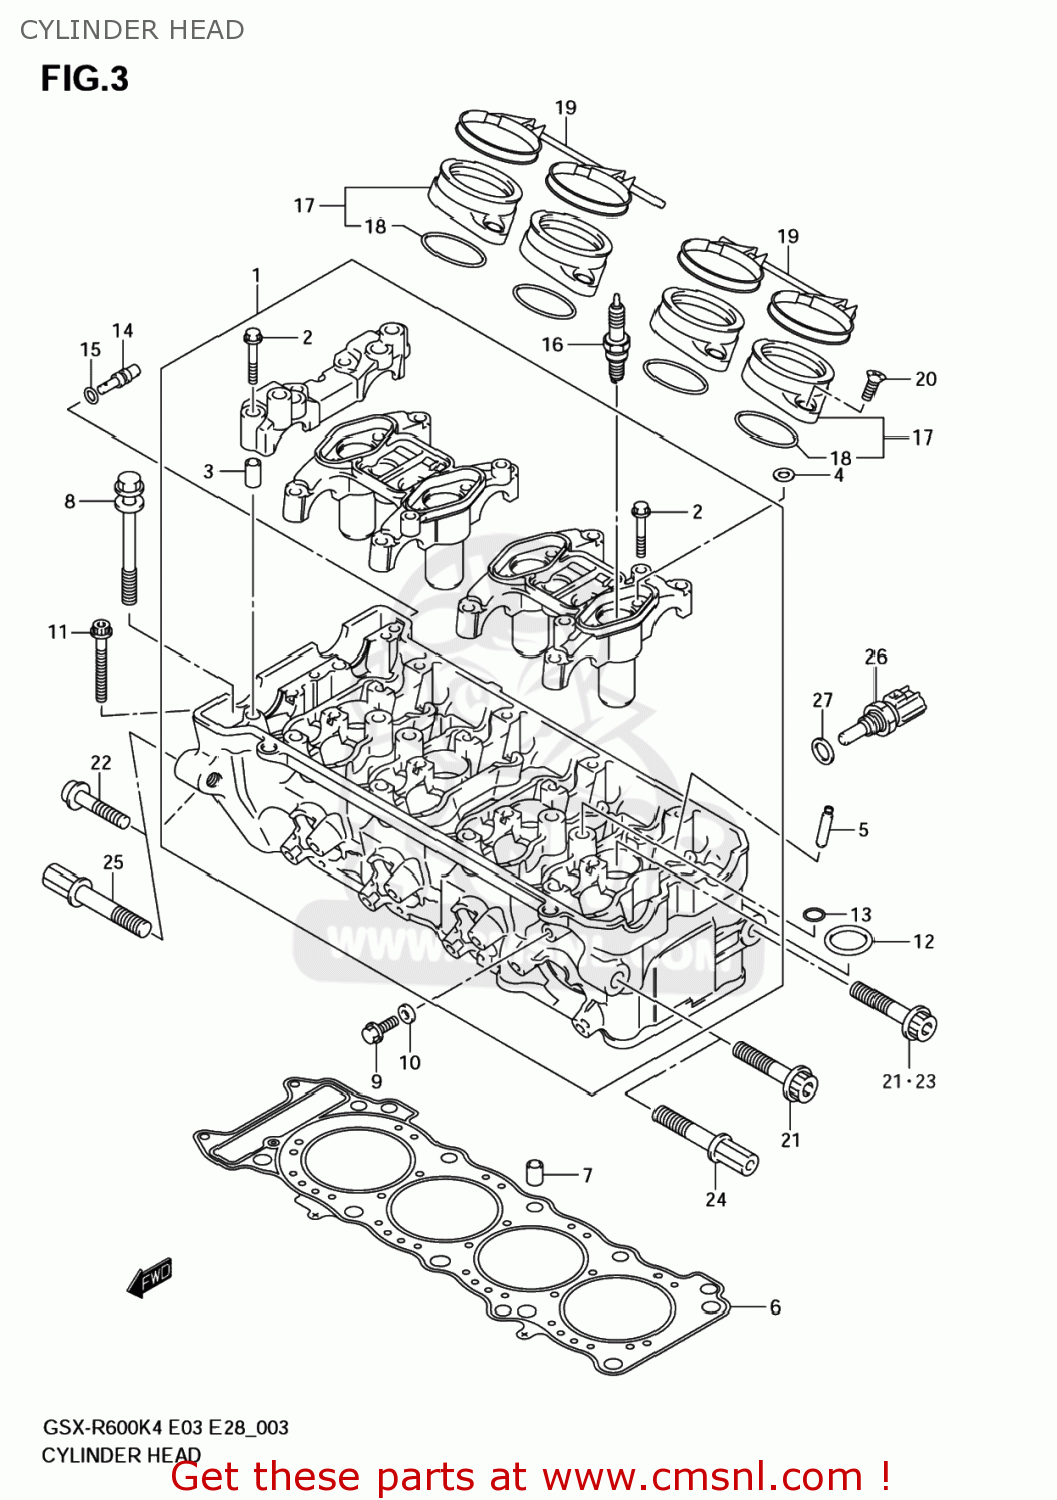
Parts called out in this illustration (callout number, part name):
1	HEAD ASSY,CYLINDER
2	BOLT(6X40)
3	PIN(6.2X8X16)
4	GASKET(6.2X13X1.2) (NAS)
5	GUIDE,VALVE(OS:0.3)
6	GASKET,CYLINDER HEAD (NAS)
7	PIN
8	BOLT,CYLINDER HEAD
9	BOLT(6X12)
10	GASKET(5.8X13X1.2) (NAS)
11	BOLT,CYL.OIL P
12	O-RING
13	O RING(D:2.4,ID:11)
14	JET(8)
15	O RING(D:1.2,ID:4)
16	PLUG,SPARK(CR8E)
17	PIPE ASSY,INTAKE
18	O RING(D:2.4,ID:41.7)
19	CLAMP COMP,INT
20	SCREW ,6X16
21	BOLT(10X45)
22	BOLT(10X55)
23	BOLT(10X45)
24	BOLT,ENGINE MOUNTING HEAD
25	BOLT,ENGINE MOUNTING HEAD
26	SENSOR,WATER TEMP
27	GASKET(12X17X1) (NAS)
